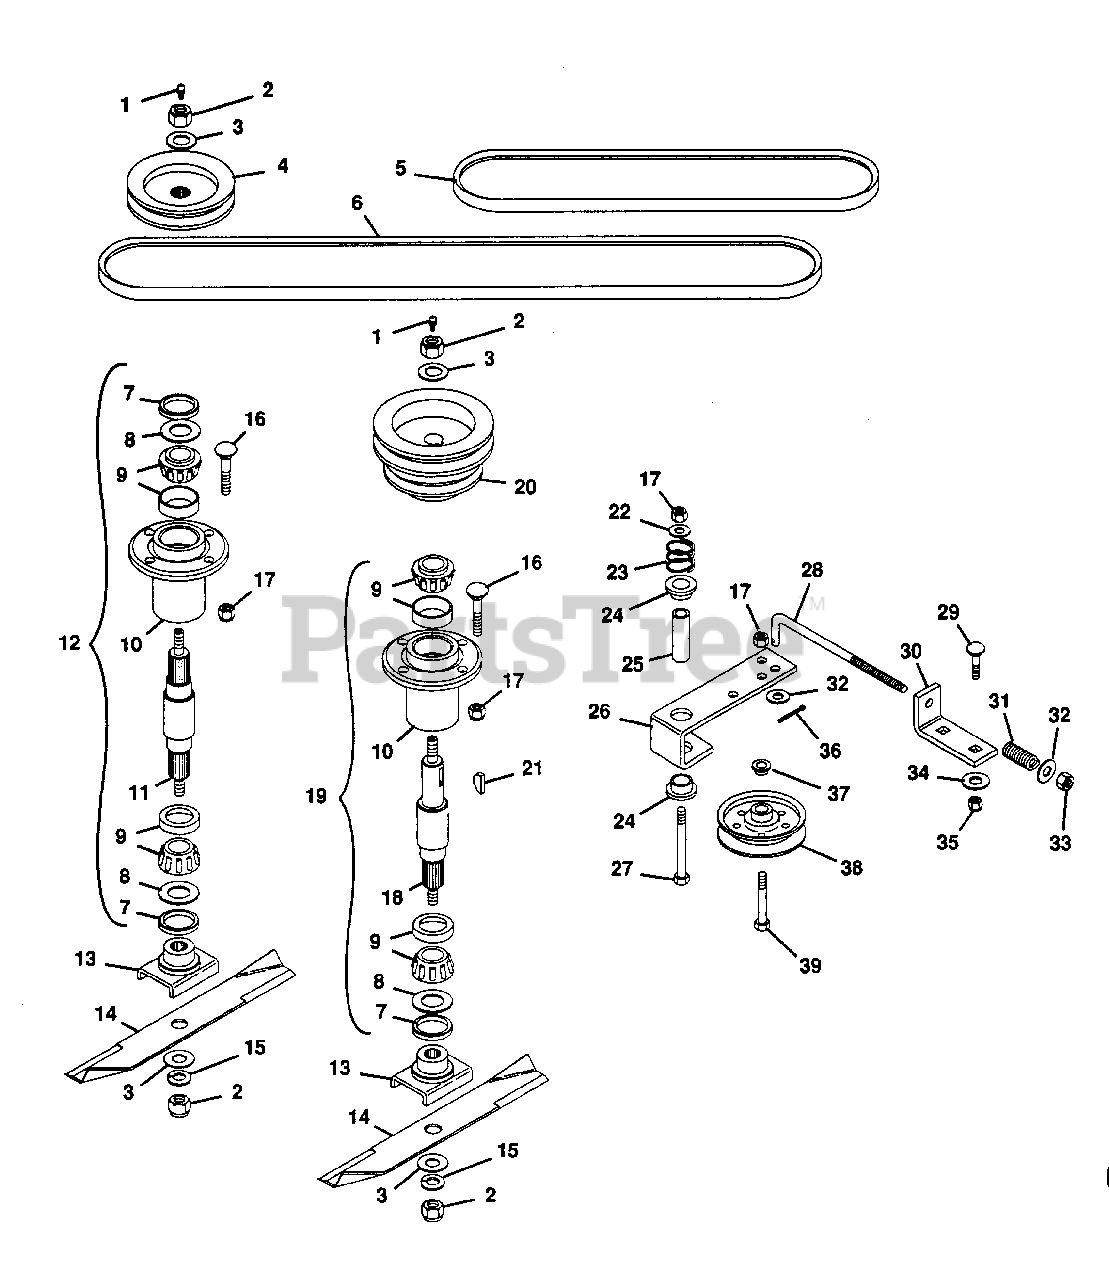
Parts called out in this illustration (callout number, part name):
1	Fitting, Lube 1/8
2	Nut, Lock 5/8-11
3	Wshr, Flat .687x1.312x.122/.146
4	Sheave, Spindle
5	Belt, Mower Drive
6	Belt, 50" GEM
7	Seal, Steel(in 21306)
7	Seal, Steel(in 34605)
8	Washer, Flat .975x1.970x.030(in 21306)
8	Washer, Flat .975x1.970x.030(in 34605)
9	Assembly, Bearing
10	Housing, Bearing
11	Shaft, Spindle
12	Assembly, Spindle
13	Weldment, Blade Cradle
14	Blade
15	Washer, Lock 5/8 SP
16	Bolt, 3/8-16x1.50 Rd Hd Sq Nk
17	Nut, Lock 3/8-16
18	Shaft, Spindle
19	Assembly, Spindle
20	Pulley, Drive 50"
21	Key, Woodruff .250x1.00 HRD #15
22	Washer, Flat .438x1.000x.083
23	Spring, Comp. 1x.80x36 Lb/In
24	Bush., Flg. .764x1.47x.560 Ny.
25	Bush., St. .437x.750x2.44 Stl.
26	Arm, Idler Pivot
27	Bolt, Hex 3/8-16x3.75
28	Rod, Idler
29	Bolt, Carriage 5/16-18x1.00
30	Bracket, Idler Rod
31	Spring, Comp. 1x.78x338 Lb/In
32	Washer, Flat .406x.812x.065
33	Nut, Lock 3/8-24
34	Washer, Flat .344x.688x.065
35	Nut, Lock 5/16-18
36	Pin, Cotter 3/32x1.00
37	Bush., St. .406x.750x.188 Stl.
38	Sheave, Idler
39	Bolt, Hex 3/8-16x2.25
